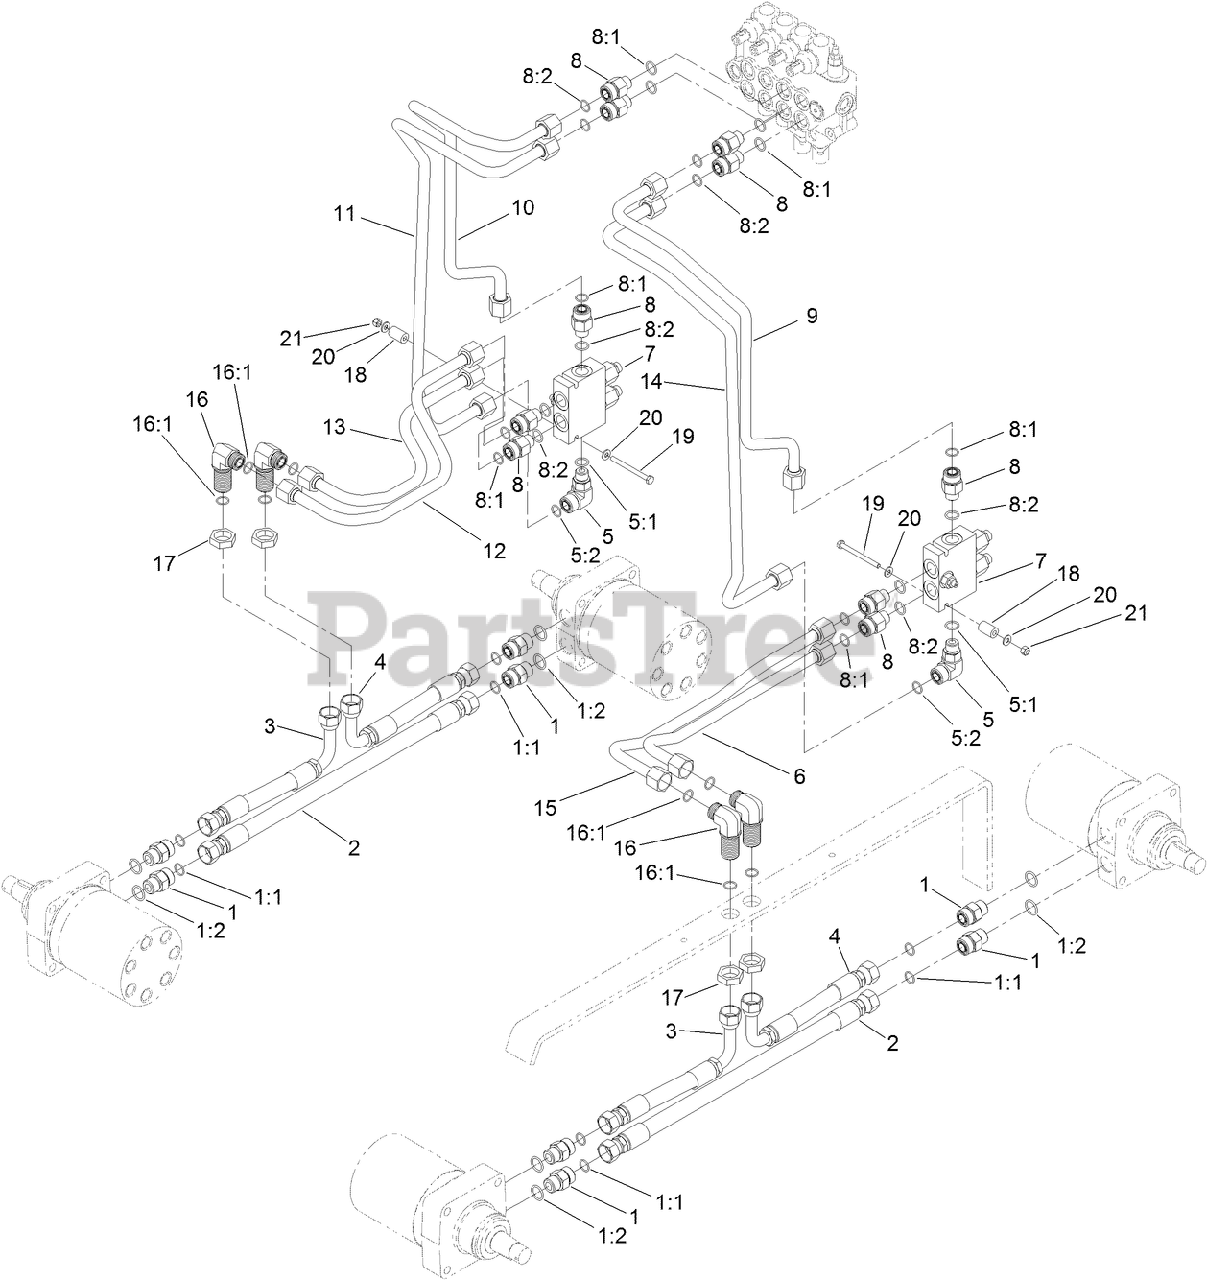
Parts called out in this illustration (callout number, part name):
1	FITTING-STRAIGHT
1:1	O-RING
1:2	O-RING
2	HYD HOSE ASM
3	HYD HOSE ASM
4	HYD HOSE ASM
5	Fitting-Elbow, 90 DEG
5:1	O-RING
5:2	O-RING
6	HYD TUBE ASM
7	HYD COUNTERBALANCE VALVE ASM
8	FITTING-STR
8:1	O-RING
8:2	O-RING
9	HYD TUBE ASM
10	HYD TUBE ASM
11	HYD TUBE ASM
12	HYD TUBE ASM
13	HYD TUBE ASM
14	HYD TUBE ASM
15	HYD TUBE ASM
16	FITTING-BULKHEAD, 90 DEG
16:1	O-RING
17	NUT-LOCK, BULKHEAD
18	SPACER-VALVE
19	SCREW-HH
20	WASHER-FLAT
21	NUT-LOCK, NI
